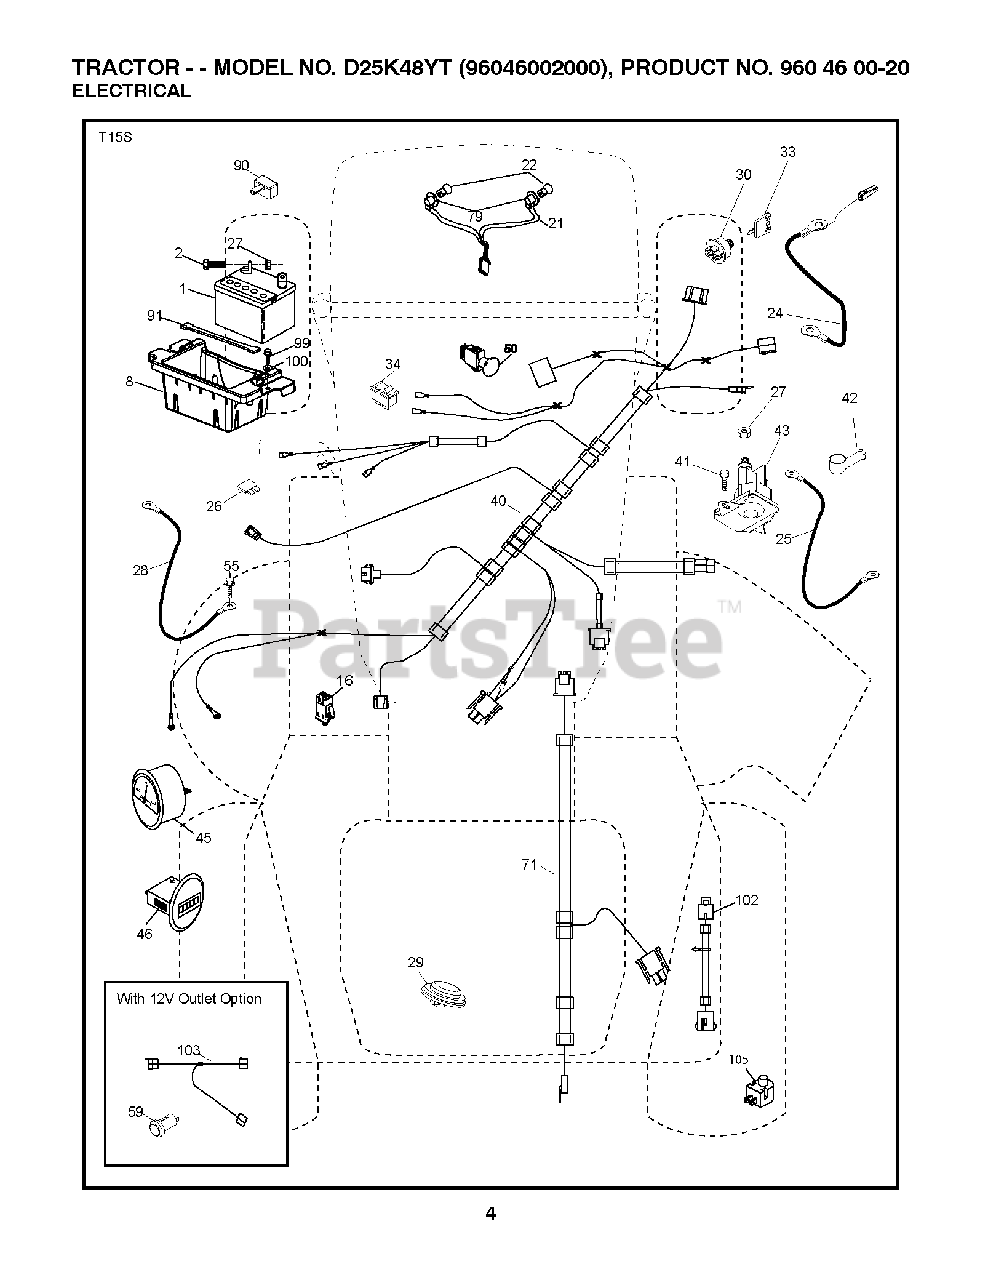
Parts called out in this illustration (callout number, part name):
1	REPL BY 532 12 38-99
2	BOLT.HEX.1/4.X.3/4.DICHROMATE
8	BOX.BATTERY.MOUNT.FRONT.LT
16	SWITCH INTERLOOK PUSH-IN
21	HARNESS.W/LIGHT SOCKET
22	LIGHTBULB
24	CABLE.BATT.POS.WIRE.TG.DA SOL
25	CABLE.STARTER.6GA.BL/RED.14.
26	FUSE 20AMP
27	NUT
28	CABLE GROUND 6 GA 21" 90T BLK
29	SWITCH.SEAT.DELTA.OPC.
30	SWITCH.IGN.DELTA.W.LGH.ROS
33	KEY.CHAIN.BLISTER.PACK.GEN.INT
34	SWITCH LT
40	HARNESS IGN. DASH
41	SCREW
42	TERMINAL COVER
43	SOLENOID.W/BRASS.PLUNGER
45	AMMETER.ROUND.SNAPIN
46	HOURMETER.ROUND.SNAPIN
50	PTO SWITCH
55	SCREW 5/16"
71	HARNESS-CHASSIS SUB
79	BULB HOLDER ASM.
90	COVER.TERMINAL.BATTERY
91	STRAP.BATTERY.MOUNT.FRONT
99	SCREW HEXWSHR 1/4-20X3/4
102	HARNESS PIGTAIL PCH TEX ROS
105	REVERSE SWITCH
